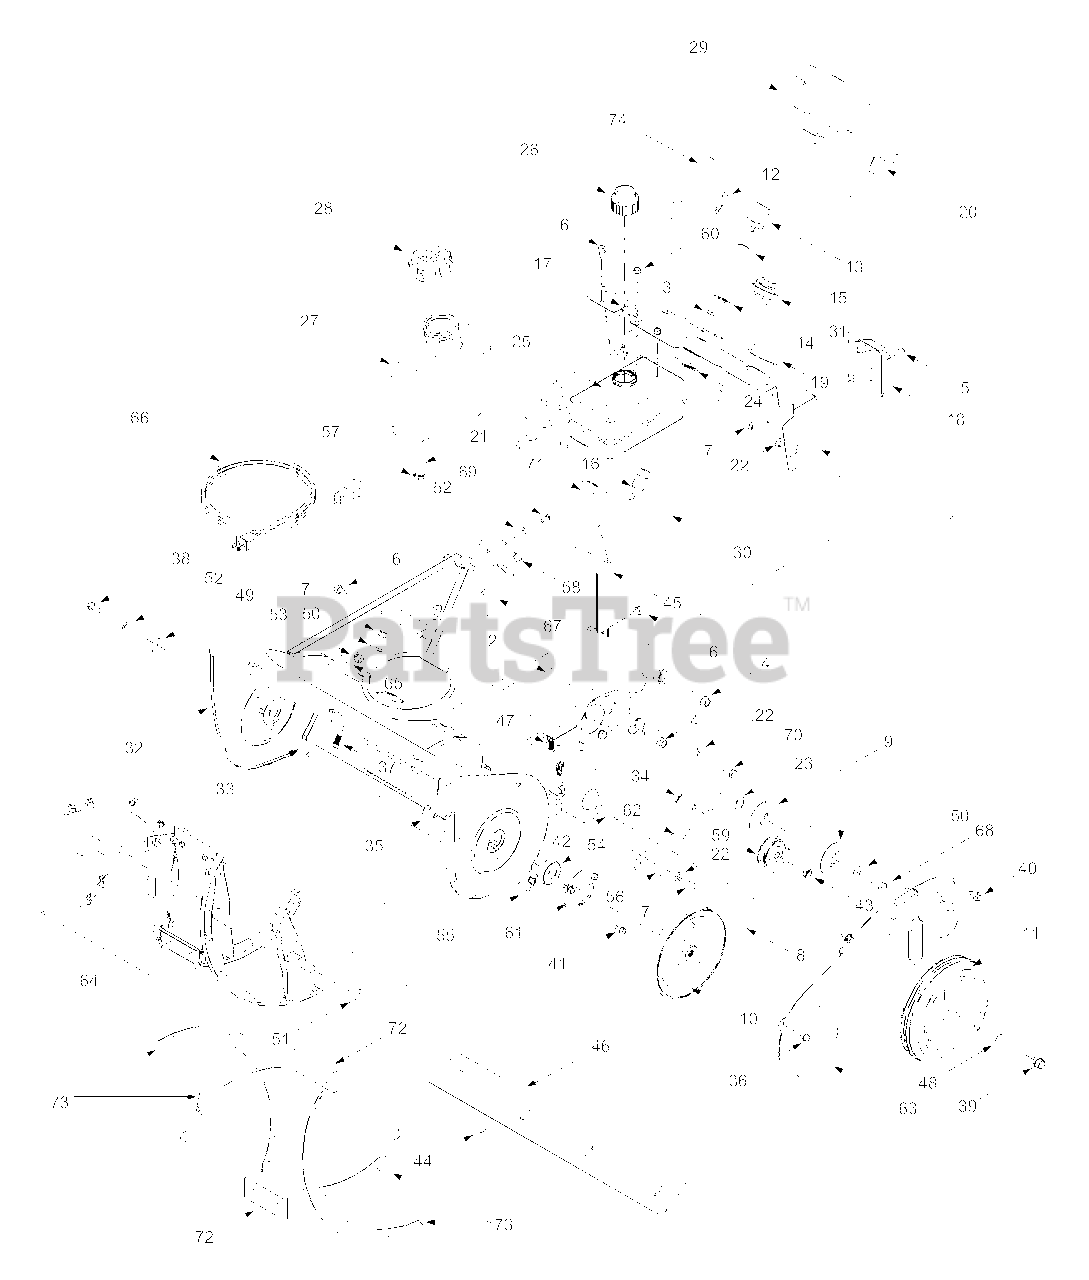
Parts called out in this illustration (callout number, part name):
3	Screw, #10-16 x .625
4	Hex Flange Screw, 5/16-18 x 1.25
5	Screw, #10-16 x .375
6	Self-tapping Screw, 1/4-20 x .625
7	Hex Nut, 5/16-18
8	Drive Belt
9	Pulley Half-.625 x 2.25
10	Auger Drive Pulley
11	Wheel Assembly, 7 x 1.5
12	Ignition Key
13	Ignition Key w/ Plastic Cover
14	Jam Nut, 5/8-32
15	Ignition Switch Cap
16	Ignition Switch
17	Chute Crank Bracket
18	Choke Cover
19	Spark Plug Cap
20	Recoil Handle
21	Fuel Line Hose
22	Lock Washer, 5/16
23	Spacer, .630 x .88 x .680
24	Internal Lock Washer, 5/8 x 1.058 x .046
25	Gas Tank, 1 qt
26	Fuel Cap
27	Gas Tank, 2 qt.
28	Fuel Cap
29	Recoil Handle (Mitten Grip)
30	Primer Tube
31	Primer Bulb
34	Cap Screw, 3/8-24 x 1.25
35	Trus Machine Screw, 5/16-18 x .75
36	Hex Index Washer Screw, 1/4-14 x .375
37	Carriage Bolt, 5/16-18 x .75
38	Self-tapping Screw 1/4-20 x .75
39	Self-tapping Screw 3/8-16 x .50
40	Self-tapping Screw, 1/4-14 x .625
41	Self-tapping Screw, 1/4-14 x .50
42	Axle, .35 x .5 x 20.75
43	Jam Lock Nut, 3/8-24
44	Hex Flange Lock Nut, 1/4-20
47	Extension Spring, .33 x 1.12
48	Flat Washer, .51 x .75 x .033
49	Flat Washer, .265 x .938 x .120
50	Belleville Washer, .340 x .872
51	Flat Washer, .51 x 1.0 x .125
52	Lock Washer, 1/4
53	Plastic Bushing
54	Ball Bearing, 17mm x 40mm x 12mm
55	Cable, 41.78"
56	Shoulder Spacer
57	Hose Clamp, .49
58	Plastic Bushing, .38
59	Flat Idler Pulley, 1.88 x .50 x 2.12
60	Hi-Lo Self-tapping Screw, 1/4-15 x .75
61	Bearing Cup
62	Brake Idler Bracket
64	Solid Shaft Auger Assembly
65	Chute Crank Bracket
66	110V Extension Cord, 2-prong
67	Fuel Tank Support Bracket
68	Hex Cap Screw, 5/16-24 x .75
69	Hex Cap Screw, 1/4-20 x .50
70	Hex Cap Screw, 5/16-18 x 1.50
71	Self-adhesive Clamp, .5
72	Rubber Paddle
73	Rubber Paddle/Spiral
74	Chute Crank Assembly
